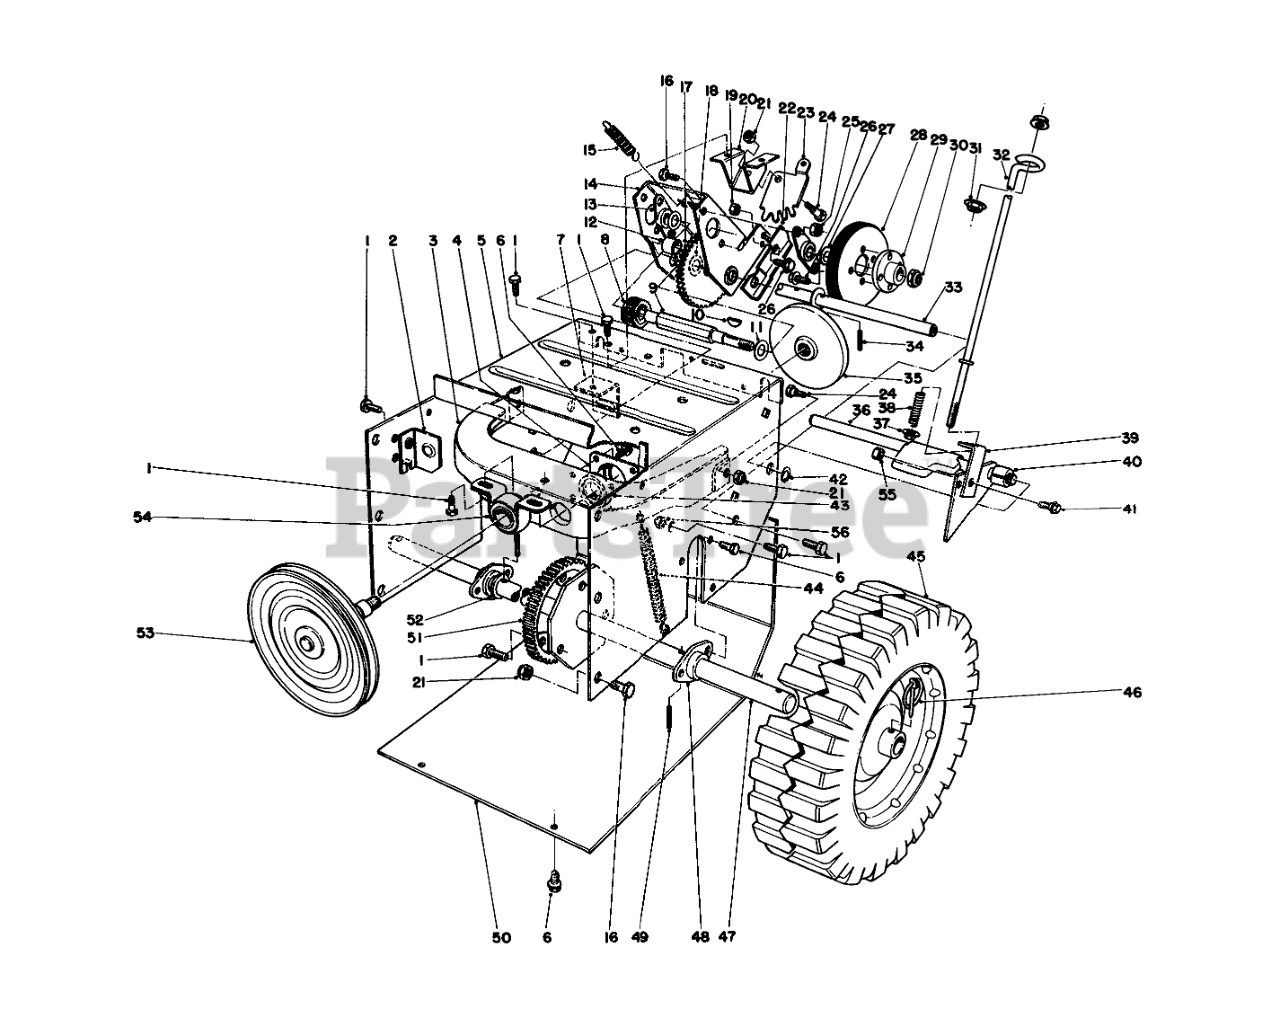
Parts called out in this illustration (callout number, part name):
1	SCREW-HWHTF
2	AUGER CLUTCH MTG FRT
3	"OBS" FRICTION PLT FRAME
4	CUP-BEARING
5	Frame-Traction
6	SCREW
7	BRACKET-MOUNT, REAR
8	PINION
9	SHAFT-WHEEL, FRICTION
10	KEY-WOODRUFF
11	WASHER-FLAT
12	5/8ID X 1LG BUSHING
13	BEARING-WHEEL, FRICTION
14	BRACKET-SLIDING
15	SPRING-TRACTION
16	SCREW-HH
17	Intermediate Gear & Bushing (Incl. Ref. #12)
18	WASHER-SPECIAL
19	NUT-LOCK, NI
20	MOUNT-LEVER
21	NUT-LOCK, NI
22	CAM-RECEIVER
23	GEAR-QUADRANT
24	BOLT-SHOULDER
25	NUT-LOCK, CONE
26	Screw
27	WASHER-THRUST
28	WHEEL-FRICTION
29	HUB-WHEEL, FRICTION
30	NUT-LOCK, NI
31	NUT-HF
32	ROD-TRACTION, LOWER
33	SHAFT-PIVOT
34	PIN-SPRING
35	PLATE-FRICTION
36	Traction Engagement Asm.
37	NUT-LOCK, HHF
38	SPRING
39	BRACKET-TRACTION
40	SPACER
41	SCREW
42	RING-RETAINING
43	BEARING-BALL
44	SPRING-PLATE, FRICTION
45	Wheel
46	PIN-LYNCH
47	AXLE SHAFT WA
48	BEARING-AXLE
49	PIN-SPRING
50	Bottom Cover
51	GEAR-AXLE
52	WASHER-THRUST
53	Pulley & Shaft
54	BUSHING ASM
55	NUT-LOCK, NI
56	NUT-LOCK, CAP
